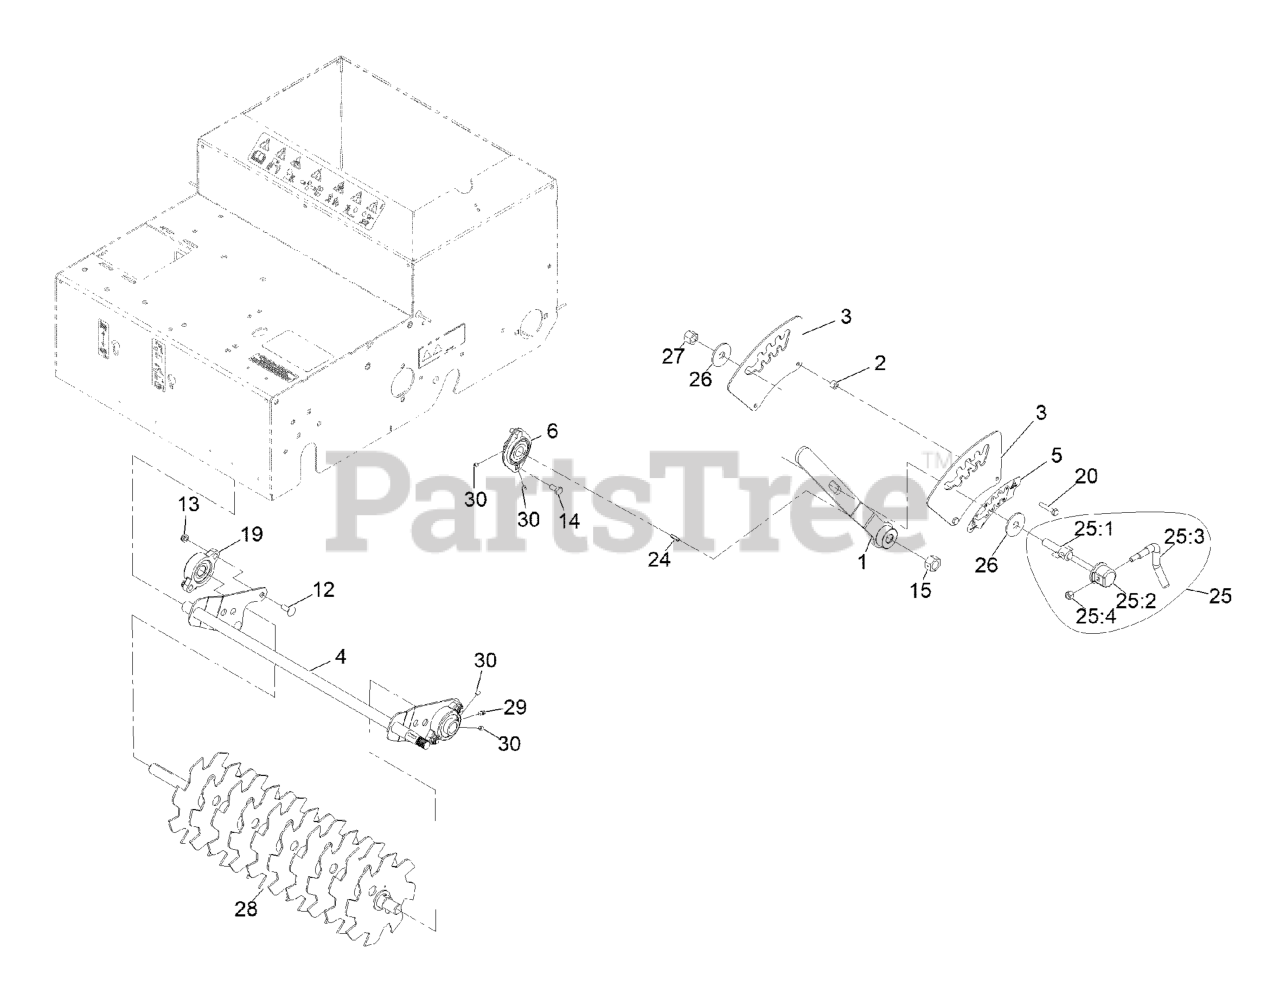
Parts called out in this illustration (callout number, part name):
1	HANDLE-HEIGHT
3	PLATE-HEIGHT
4	PIVOT-HEIGHT
5	DECAL-CUT DEPTH, SLICER/S
6	BEARING
12	SCREW-CARR
13	NUT-LOCK, NI
14	SCREW-HH
15	NUT-BLADE
19	BEARING-FLANGE
20	Screw-HH
24	KEY-WOODRUFF
25	LEVER ASM
25:1	SCREW-LOCK
25:2	CAP-LOCK
25:4	NUT-LOCK, NI
26	WASHER-THRUST
27	NUT-LOCK, NI
28	SLICER SHAFT ASM
29	FITTING-GREASE
30	SCREW-SET, HSH
